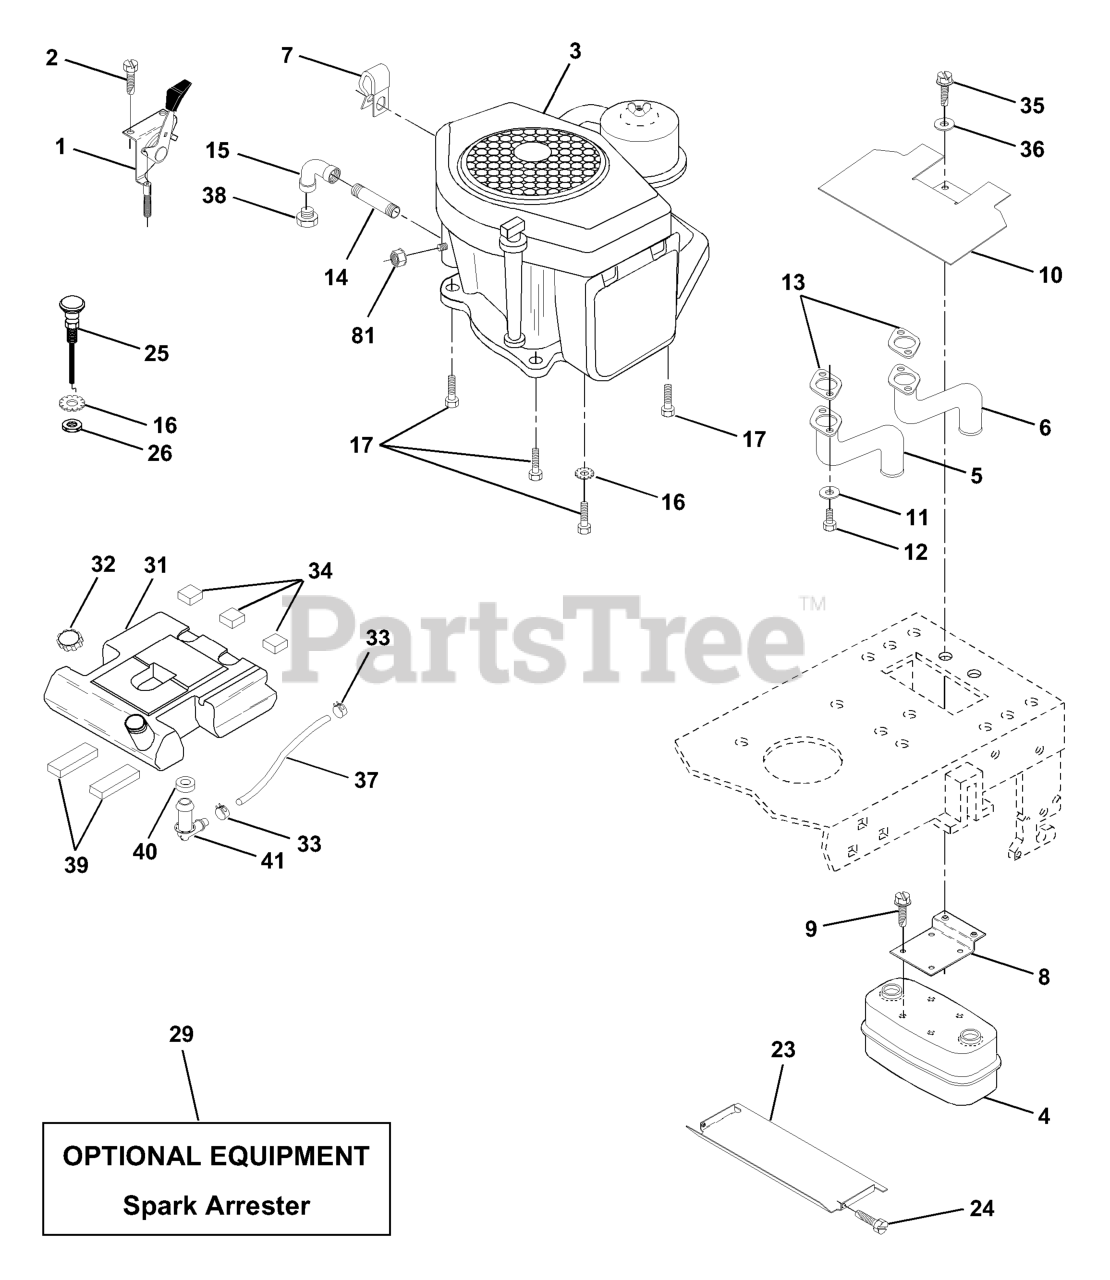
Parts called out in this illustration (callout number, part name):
1	THROTTLE CONTROL
2	SCREW LT
4	MUFFLER
5	MANIFOLD TUBE LH
6	MANIFOLD TUBE RH
7	CLIP T
8	BRACKET MUFFLER
9	SCREW ST
10	SHIELD HEAT LT
11	WASHER.LOCK.HVY.HLCL.SPR.5/16
12	Bolt, Fin Hex 1/4-20 x 3/4
13	Muffler Gasket
14	Nipple Pipe 3/8 Npt X 4-1/2"
15	ELBOW
16	LOCKWASHER
17	SCREW LT
23	HEAT SHIELD
25	CHOKE CONTROL
26	NUT
29	KIT.SPARK ARRESTOR 794945 B&S
31	FUEL TANK
32	FUEL CAP
33	HOSE CLAMP
34	PAD-SPACER LT
35	SCREW.THDROL.5/16-18X3/4.TTY
36	WASHER
37	FUEL LINE 54"
38	Plug Oil Drain
39	PAD IDLER TI
40	BUSHING OUTLET T
41	STEM FUEL TANK
81	NUT
